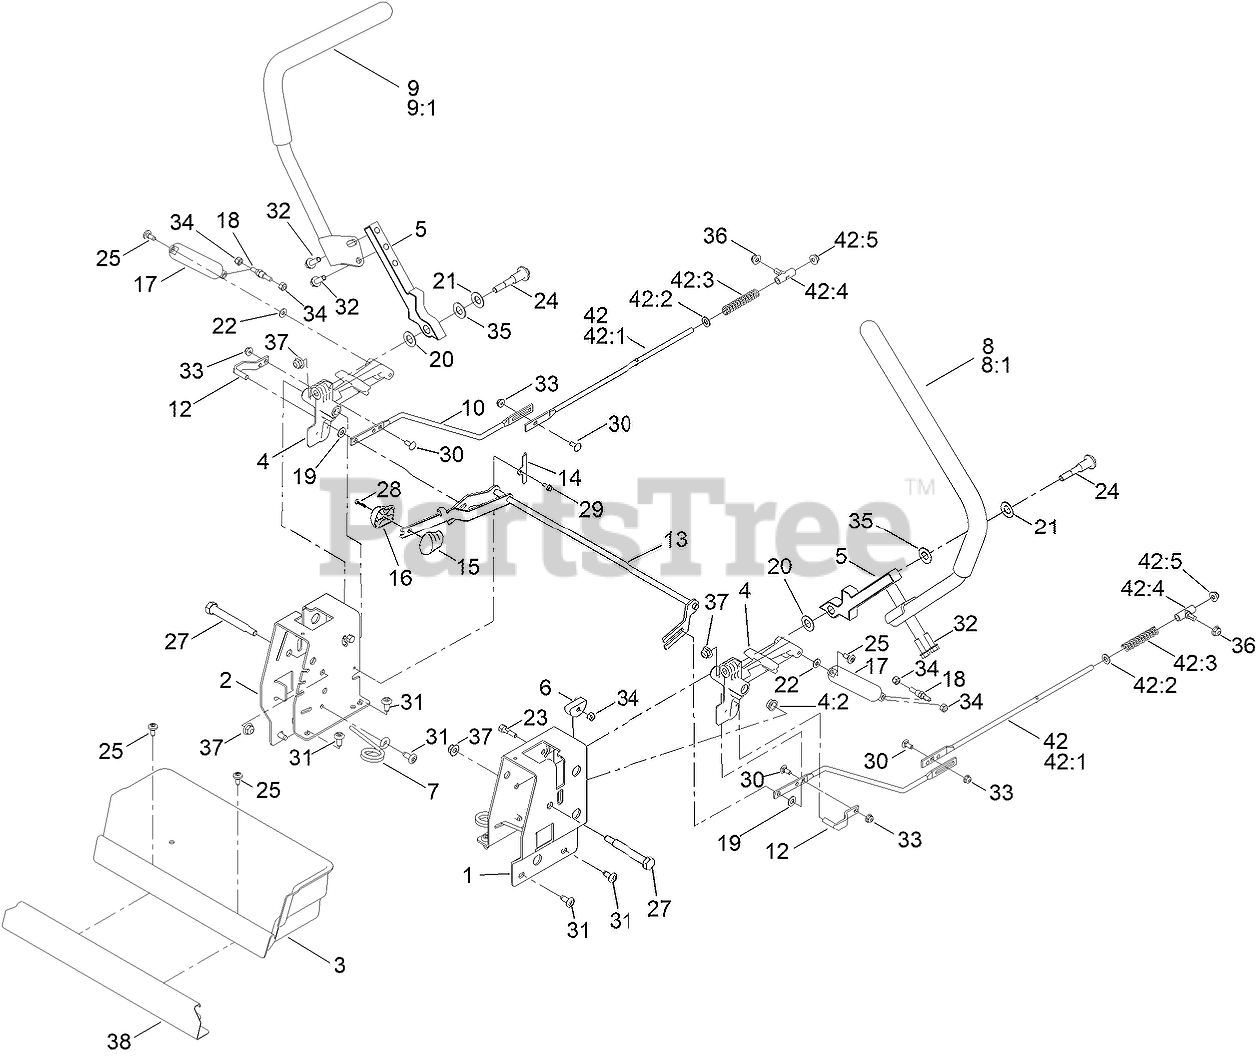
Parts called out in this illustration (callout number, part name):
1	PLATE-CONTROL BOX, LH
2	PLATE-CONTROL BOX, RH
3	BOX-STORAGE
4	ACTUATOR ARM ASM
4:2	BUSHING-FLANGE
5	ARM-CONTROL
6	ECCENTRIC
7	SPRING-TORSION
8	HANDLE-CONTROL, LH
9	HANDLE-CONTROL, RH
10	ROD-HYDRO, FRONT
12	PIN-ROD, HYDRO
13	SPEED CONTROL ASM
14	PLATE-RETAINER
15	KNOB-RH
16	KNOB-LH
17	DAMPER-NON CAVITATING
18	STUD-DAMPER
19	SPACER-NYLON
20	WASHER-NYLON
21	WASHER-BELLEVILLE
22	WASHER
23	BOLT-PIVOT, ECCENTRIC
24	BOLT-PIVOT
25	SCREW-SHOULDER
27	BOLT-PIVOT
28	SCREW-PPH
29	SCREW-TAPTITE
30	BOLT-CARR
32	SCREW-HHF
33	NUT-HF
34	NUT-HEX
35	WASHER
36	NUT-HF
37	NUT-HF, NI
38	PLATE-KICK
42	ROD HYDRO ASM
42:1	ROD-HYDRO, REAR
42:2	WASHER-PLAIN
42:3	SPRING-COMPRESSION
42:4	MOUNT-ROD, HYDRO
42:5	NUT-HF
